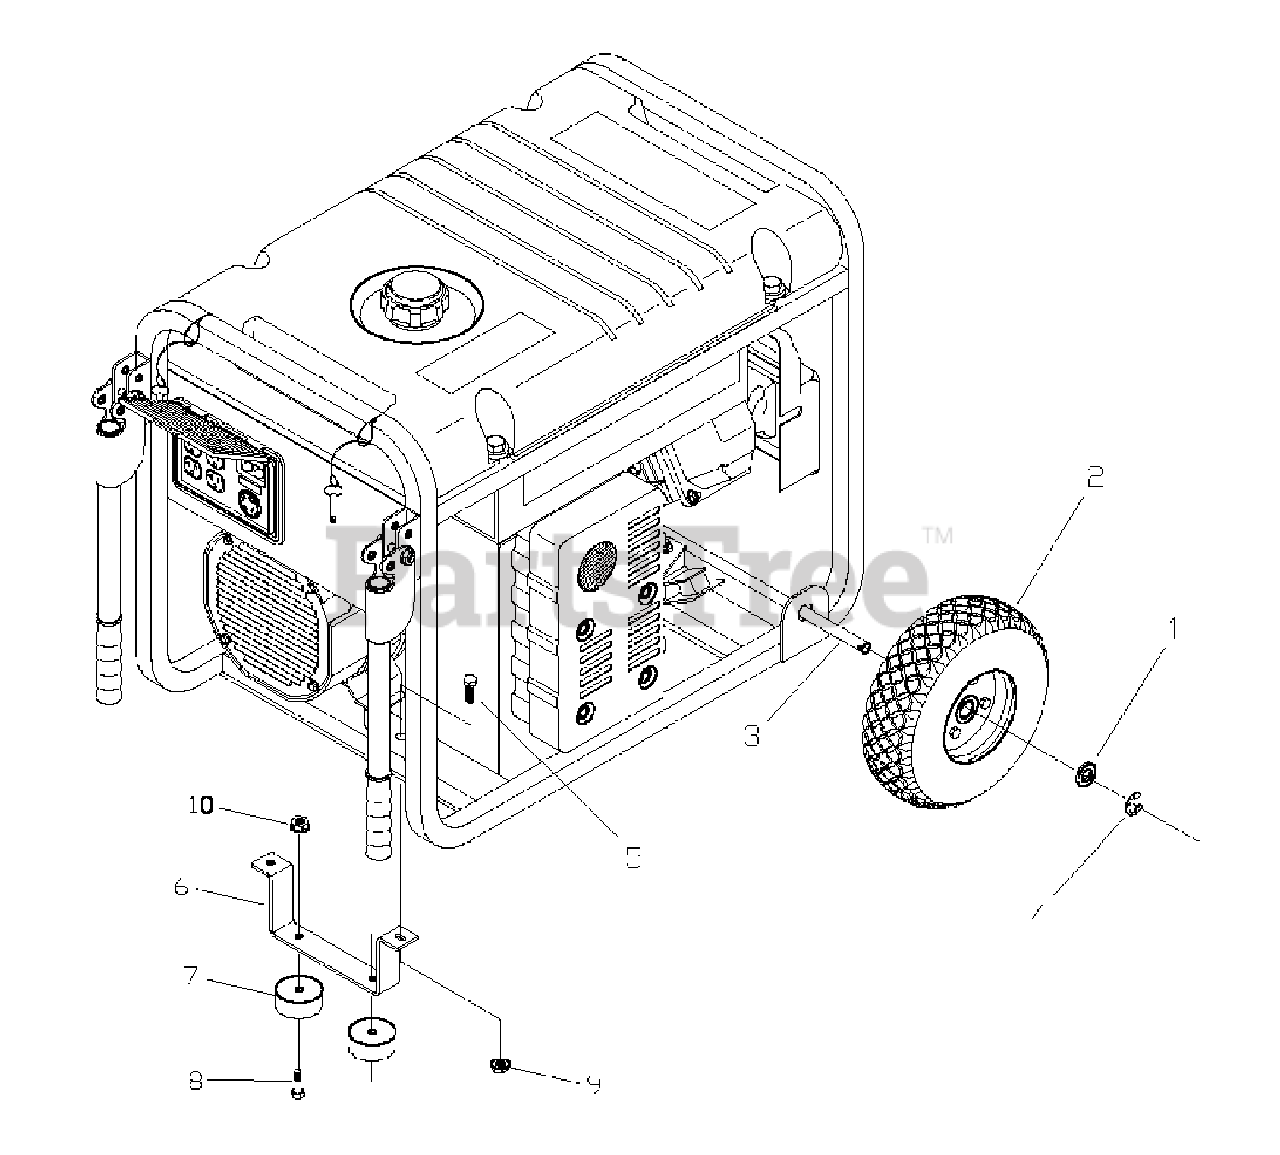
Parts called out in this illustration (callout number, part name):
2	WHEEL
3	AXLE, 5/8" x 23.62"
4	E-RING, 5/8
6	LEG, Support
7	VIBRATION MOUNT, (with washer)
9	NUT, M8 - 1.25 Lock
10	NUT, 1/4 - 20 Serrated Lock
